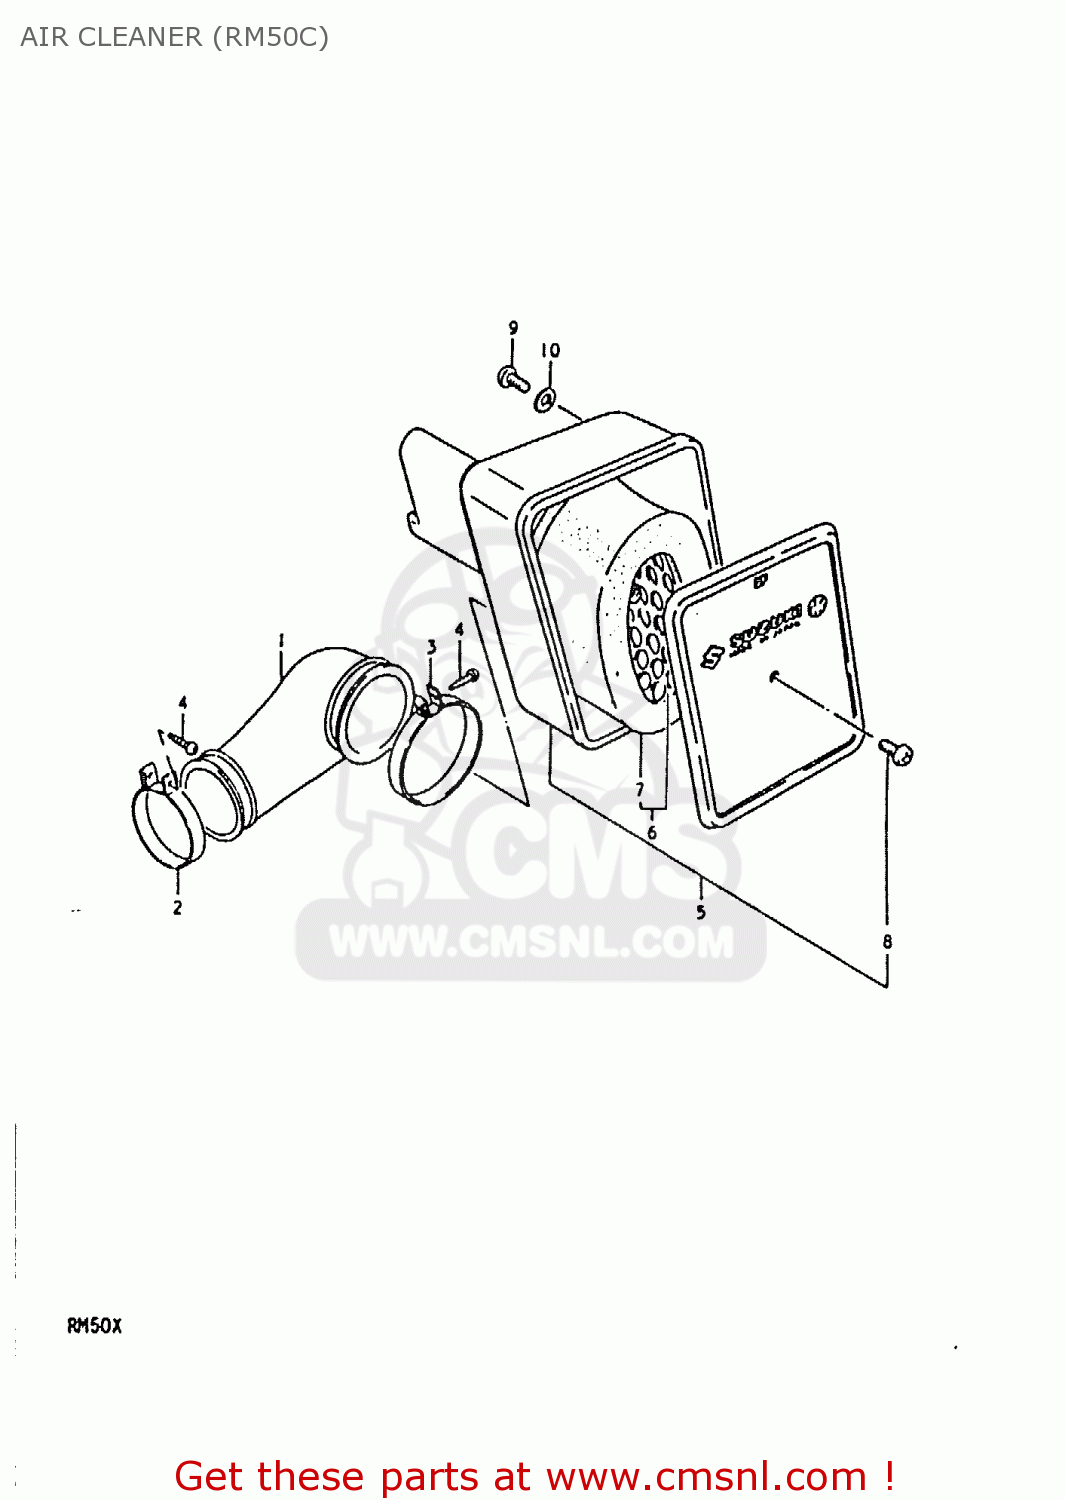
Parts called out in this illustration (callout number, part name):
1	HOSE,CARBURETOR AIR INLET
2	CLAMP
3	CLAMP
4	SCREW
5	CLEANER ASSY,AIR
6	FILTER
7	SCREW
8	SCREW
9	WASHER
